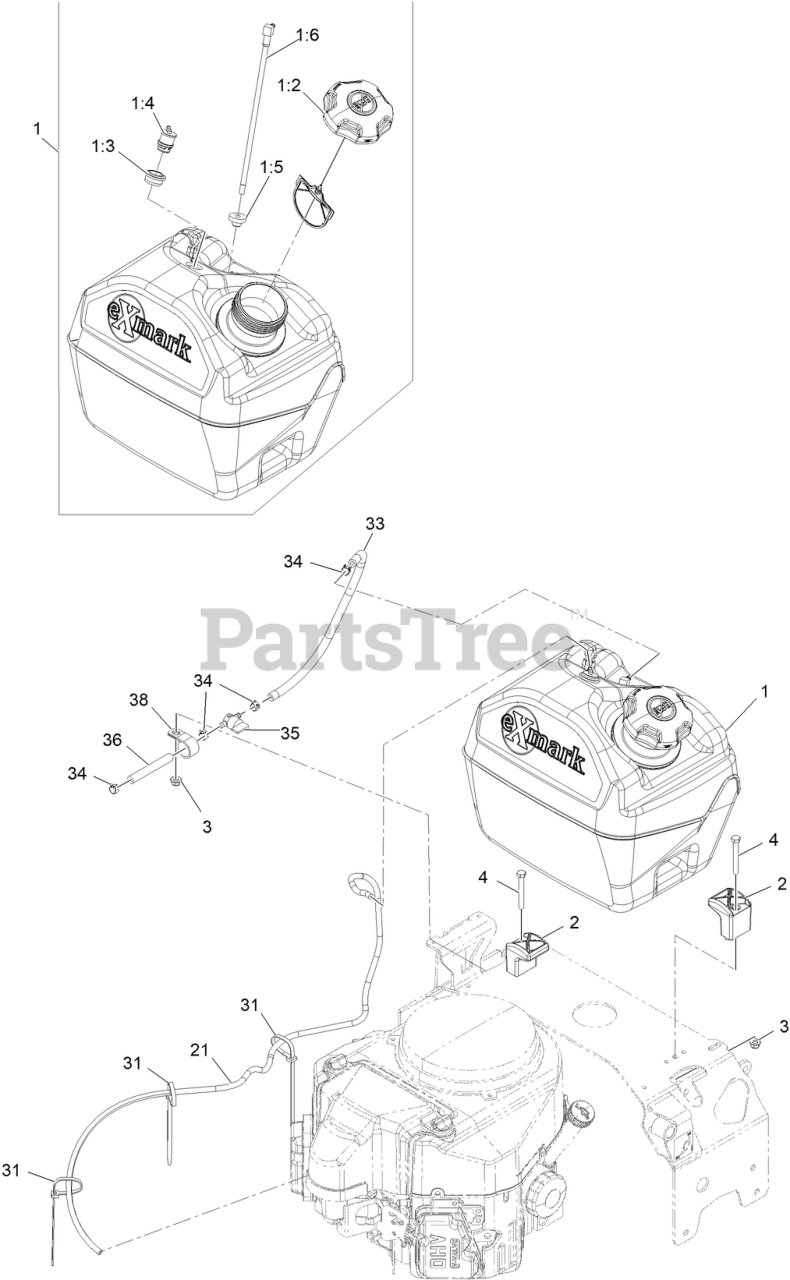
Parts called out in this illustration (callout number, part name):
1	ASM-Fuel Tank, 5 Gal, Exmark
1:2	CAP-FUEL, RATCHETING
1:3	GROMMET
1:4	VALVE-VENT, FUEL
1:5	BUSHING
1:6	FITTING, FUEL W/LINE AND SCREEN
2	CLAMP-TANK
3	NUT-HF, NI
4	SCREW-HH
21	HOSE-VENT
31	TIE-CABLE
33	HOSE-FUEL
34	CLAMP-HOSE
35	VALVE-FUEL
36	HOSE-FUEL
38	CLIP-LOOM
